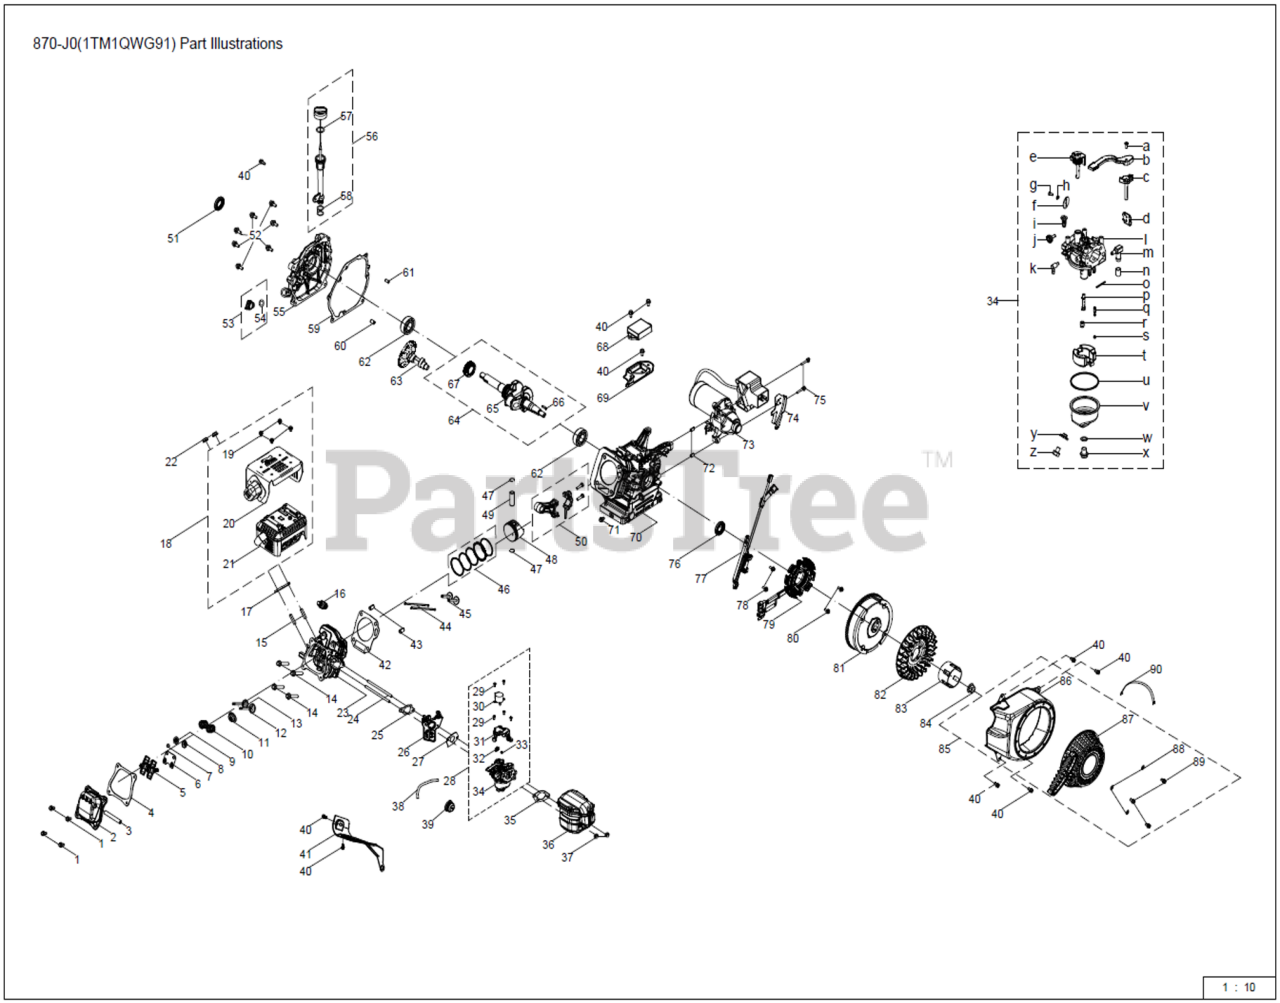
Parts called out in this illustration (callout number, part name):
1	BOLT M6 x 16
2	VALVE COVER
3	BREATHER HOSE
4	VALVE COVER GASKET
5	ROCKER ARM KIT
6	ROCKER ARM BASE
7	EXHAUST VALVE ADJUSTER
8	INTAKE VALVE SPRING RETAINER
9	EXHAUST VALVE SPRING RETAINER
10	VALVE SPRING
11	INTAKE VALVE SEAL
12	INTAKE VALVE
13	EXHAUST VALVE
14	BOLT M8-1.25 x 55 GR10.9
16	SPARK PLUG (F6RTC/RN11YC/BPR6ES)
17	MUFFLER GASKET
18	MUFFLER ASSEMBLY
19	BOLT M5-.8 x 8 CL10.9
20	OUTER MUFFLER SHIELD
21	MUFFLER ASSEMBLY
23	CYLINDER HEAD
24	STUD M6-1 x 98
25	CARBURETOR INSULATOR GASKET
27	CARBURETOR GASKET
28	CARBURETOR
29	SCREW M4x8
30	THROTTLE MOTOR
31	MOTOR BASE
32	CARBURETOR DAMPER
33	DAMPER SPRING
34	Not Serviceable/ Order Complete Assembly
35	CARBURETOR GASKET PLATE
36	HEATER BOX
38	FUEL HOSE 3.2X6.5X530
40	BOLT M6-1 x 12 GR8.8
41	AIR SHIELD
42	CYLINDER HEAD GASKET
43	PIN (10MMx16MM)
46	PISTON RING SET
47	PISTON PIN SNAP RING
50	CONNECTING ROD
54	O-RING 15.8 x 2.5
55	CRANKCASE COVER
56	DIPSTICK ASSEMBLY
58	OIL FILL TUBE O-RING
59	CRANKCASE GASKET
60	DOWEL PIN 9 X 14
61	DOWEL PIN 7 X 14
64	CRANKSHAFT (COMPLETE)
65	CRANKSHAFT
66	WOODRUFF KEY
67	DRIVE TIMING GEAR
68	SPEED REGULATOR
69	SWITCH BOX BASE
71	OIL DRAIN PLUG
73	IGNITION MODULE
74	LOWER HOUSING
75	BOLT M6-1 x 32 GR8.8
77	CHARGING COIL
78	BOLT M6-1 x 25 GR8.8
79	CHARGING COIL
80	BOLT-M6-1 x 28 GR8.8
82	COOLING FAN
83	STARTER CUP
84	FLYWHEEL NUT M14-1.5
85	Not Serviceable/ Components Only
86	BLOWER HOUSING
87	RECOIL STARTER HOUSING
88	FLAT WASHER
89	BOLT M6 x 10
90	CABLE TIE 3x150
